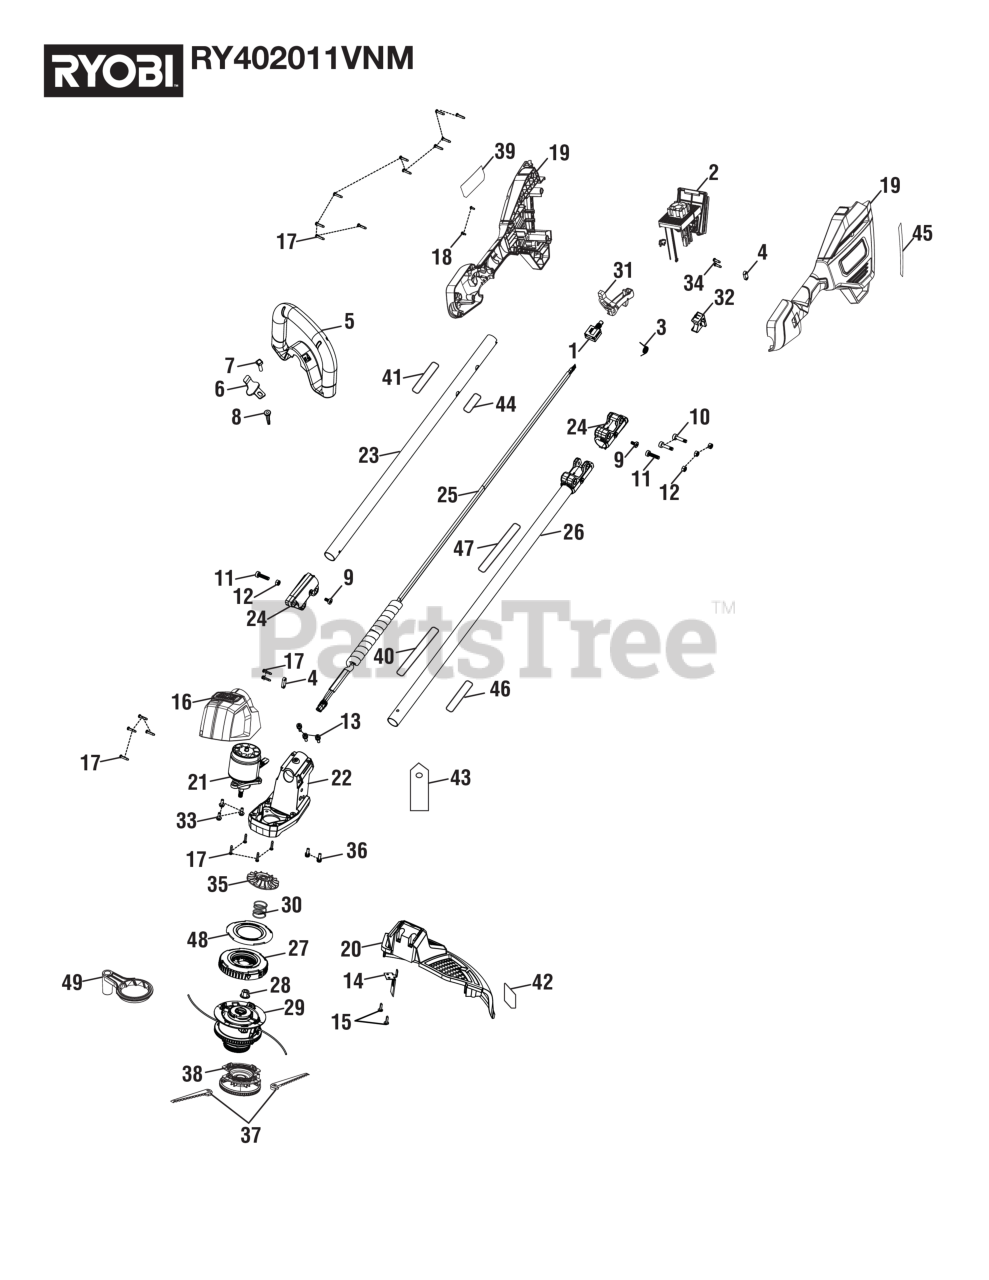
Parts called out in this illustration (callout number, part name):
1	Signal Switch
2	Electric Controller and Switch Assembly
3	Spring, Torsion, Dia 12.5mm, Music Wire
4	Wire Press Plate
5	Front Handle Assembly
6	Front Handle Clamp
7	Bolt (1/4-20 x 1 in., Square Hd.)
8	Wing Nut (1/4-20, Plastic)
9	Screw, M5.0 x 0.8 Torx T25 B, L=12mm
10	Screw (M6 x 27.5 mm)
11	Screw, M6.0 X 1 BUH, Torx 25 B, L=25mm
12	Lock Nut (M6 x 1)
13	Screw W/ Washer, Torx T25X16, M5X0.8,
14	Line Cut-off Blade
16	Motor Housing Assembly
17	Screw (M4 x 18 mm, T15 Torx Pan Hd.)
18	Screw (M3 x 8 mm, Pan. Hd.)
19	Rear Handle Assembly
20	Grass Deflector Assembly
22	Motor Bracket
23	Upper Boom Assembly
24	Coupler (Upper And Lower Boom)
25	Spring Wire
26	Lower Boom Assembly
27	Upper Housing and Locking Assembly
28	Hex Nut (M8, Left Hand Threads)
29	Lower Housing and Spool Assembly
30	Compression Spring
31	Trigger and Lock Out Button Assembly
32	High-Low Speed Switch Trigger
33	Screw, T25, M5X8, Steel, Black ZincePlat
34	Screw (M4 x 14 mm, T15 Torx Pan Hd.))
36	Screw w/Spring Washer (M5 x 15.5 mm)
37	Flail Blade
38	Fixed Line and Blade Housing Assembly
39	Data Label
40	Ryobi Whisper Logo Label
41	Icon Warning 40HP Label
42	Cutting Width Label
43	Guard Installation Tag
45	WHISPER HEAD Logo Label
46	Warning Label (French/Spanish)
47	Carbon Fiber Label
48	Front Handle Assembly
49	Crank Handle
